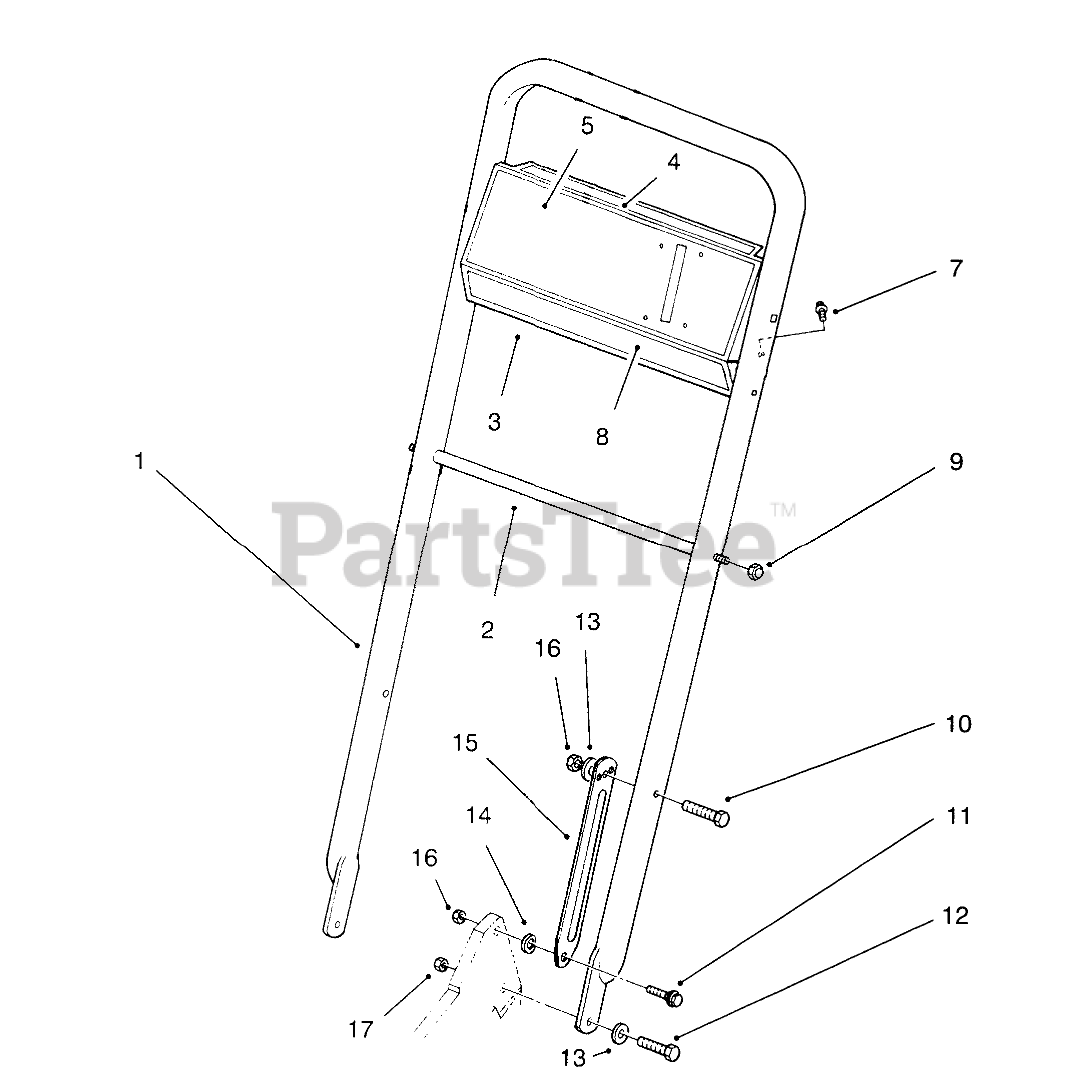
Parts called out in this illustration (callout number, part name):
1	Handle
2	ROD-SUPPORT, BAG
3	Panel-Control (Incl. Ref. #4, 5, & 8)
4	DECAL-PANEL, DANGER
5	DECAL-CONTROL PANEL
7	SCREW-HWHTF
8	DECAL-PANEL, PROLINE
9	NUT-CAP
10	SCREW-HH
11	SCREW-SHOULDER
12	SCREW-HH
13	WASHER-BELLEVILLE
14	SPACER
15	Latch-Handle
16	NUT-LOCK, NI
17	NUT-LOCK, NI
